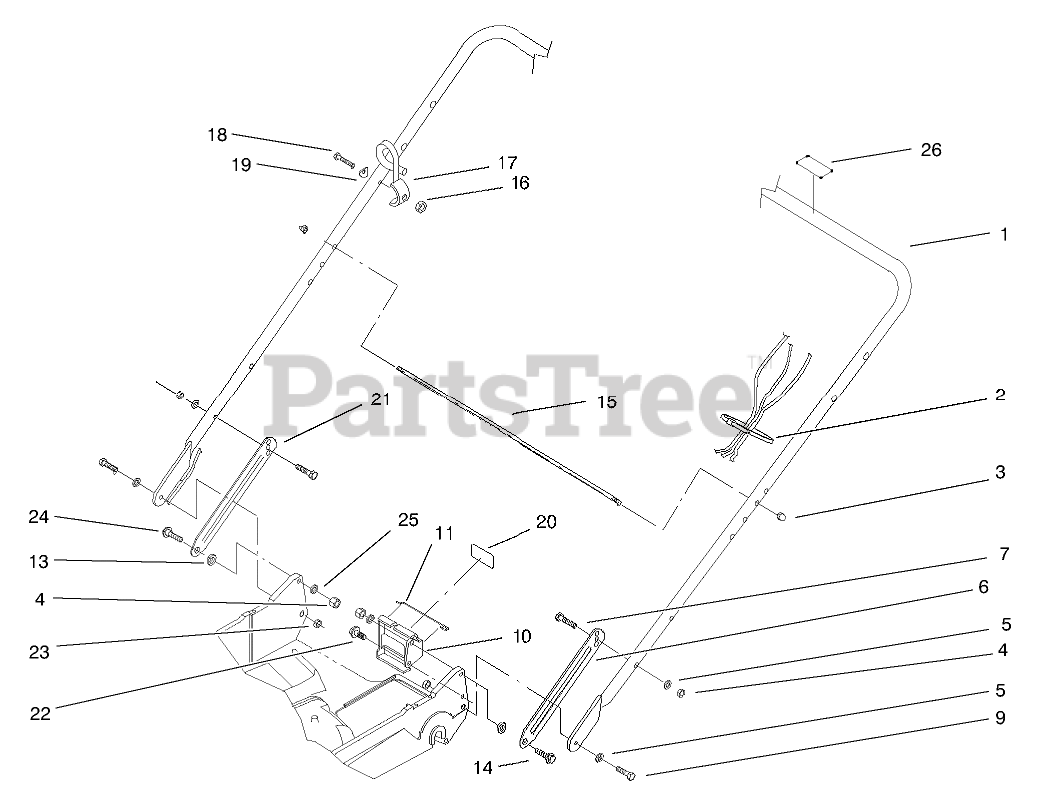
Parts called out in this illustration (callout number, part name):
2	TIE-CABLE
3	NUT-CAP
4	NUT-LOCK, NI
5	WASHER-BELLEVILLE
6	LATCH-HANDLE, LH
7	SCREW-HH
9	SCREW-HH
10	BRACKET-ADJUSTMENT, TRACTION
11	RETAINER-CABLE
13	SPACER
14	SCREW-SHOULDER
15	ROD-SUPPORT, BAG
16	NUT-LOCK, NI
17	GUIDE-ROPE
18	SCREW-HH
19	WASHER
20	DECAL-POSITION, GEAR
21	LATCH-HANDLE, RH
22	SCREW-HWHTF
23	NUT-LOCK, NI
24	SCREW-SHOULDER
25	WASHER-PLAIN
26	DECAL-PROTECTION, EAR
